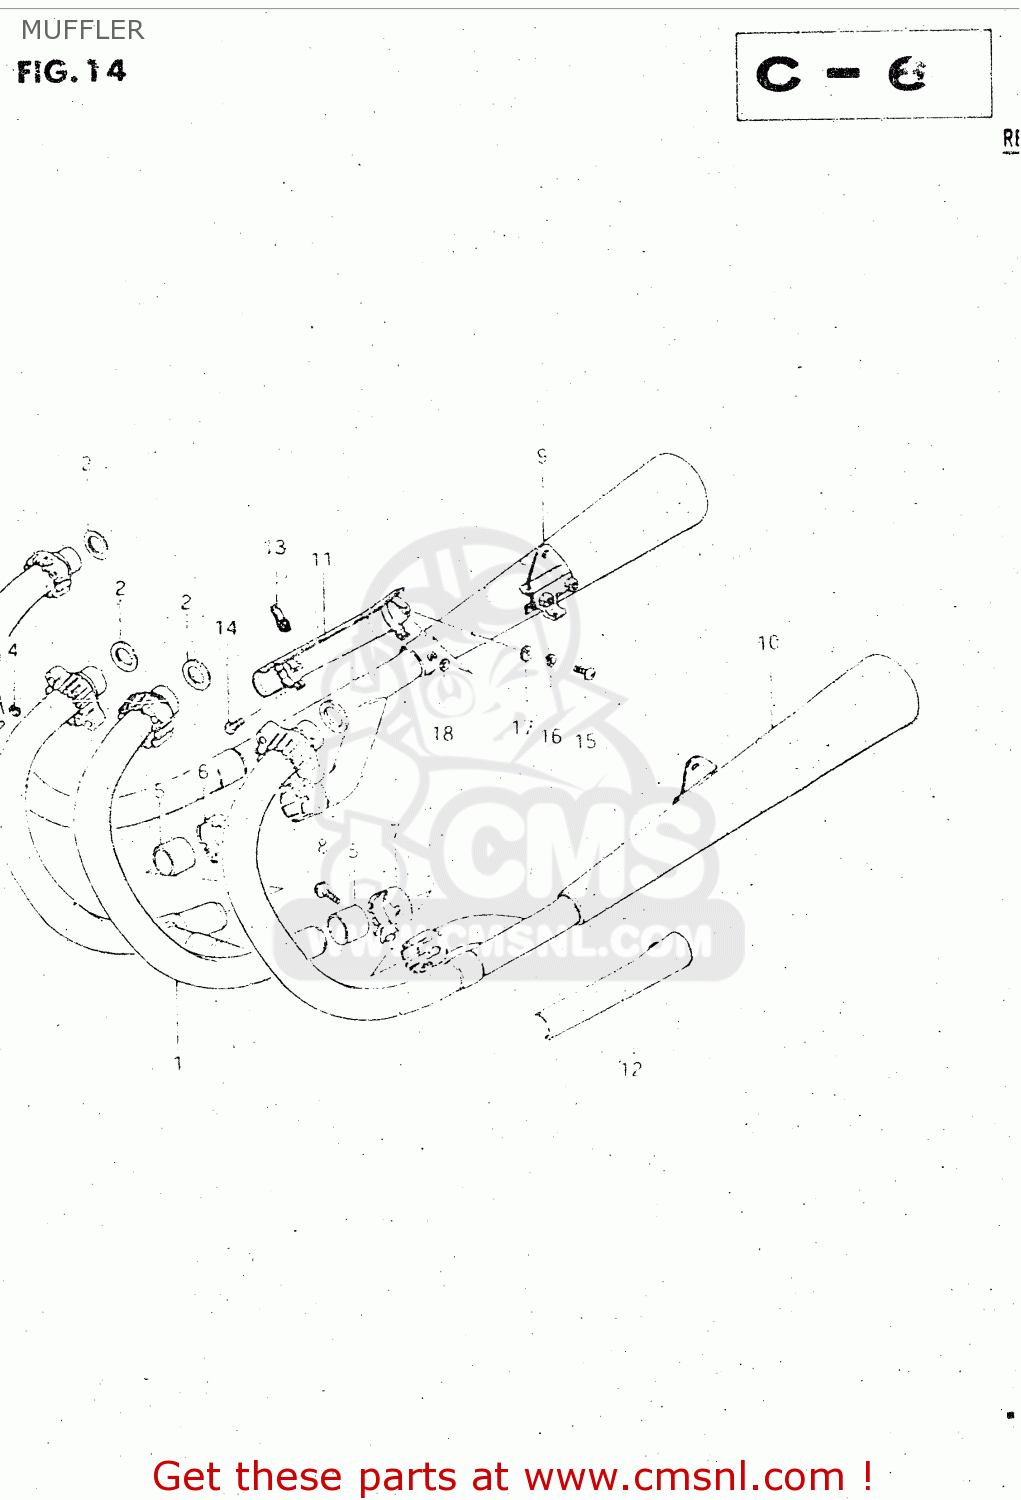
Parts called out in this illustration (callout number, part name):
1	PIPE,EXHAUST,CENTER
2	GASKET,EXHAUST PIPE (NAS)
3	BOLT
4	LOCK WASHER
5	CONNECTOR,MUFFLER
6	CLAMP,MUFFLER CONNECTOR,R
7	CLAMP,MUFFLER CONNECTOR,L
8	BOLT
9	MUFFLER, RH
10	MUFFLER, LH
11	COVER,MUFFLER,RIGHT
12	COVER,MUFFLER,LEFT
13	CLAMP,MUFFLER COVER
14	SCREW
15	SCREW 6X12
16	LOCK WASHER
17	WASHER
18	GASKET 6.2X12X1.5 (MCA)
